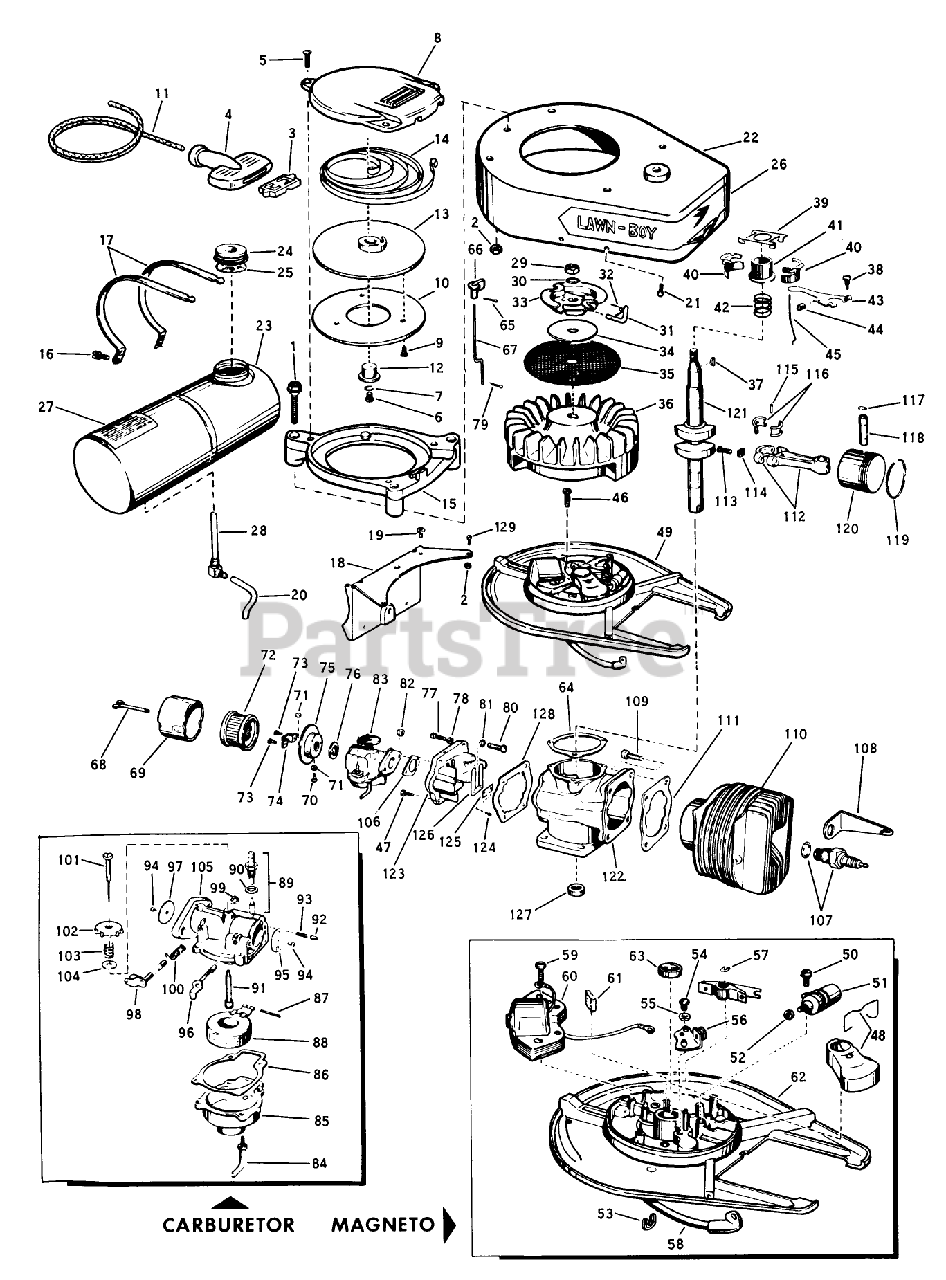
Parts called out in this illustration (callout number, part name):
10	Plate-Pulley
14	RECOIL SPRING
21	SCREW S
26	Decal-"LAWN-BOY"
28	VALVE&SCREEN SM
31	PIN - STARTER
41	COLLAR S
43	GOVERNER LEVER AY
44	WEAR BLOCK S
45	GOVERNOR ROD S
47	SCREW S
56	BREAKER AY. S
64	GASKET S
65	Cotter Pin-Choke Knob
66	KNOB, CHOKE BAR
77	SCREW S
79	Cotter Pin
82	STOP NUT
94	Screw-Choke Disc
101	NEEDLE AY. S
103	Spring-Ndl. Adj.
104	Washer
106	GASKET S
107	Spark Plug
111	GASKET S
116	LINER ASM
121	Crankshaft
125	PLATE-BACKUP, REED
